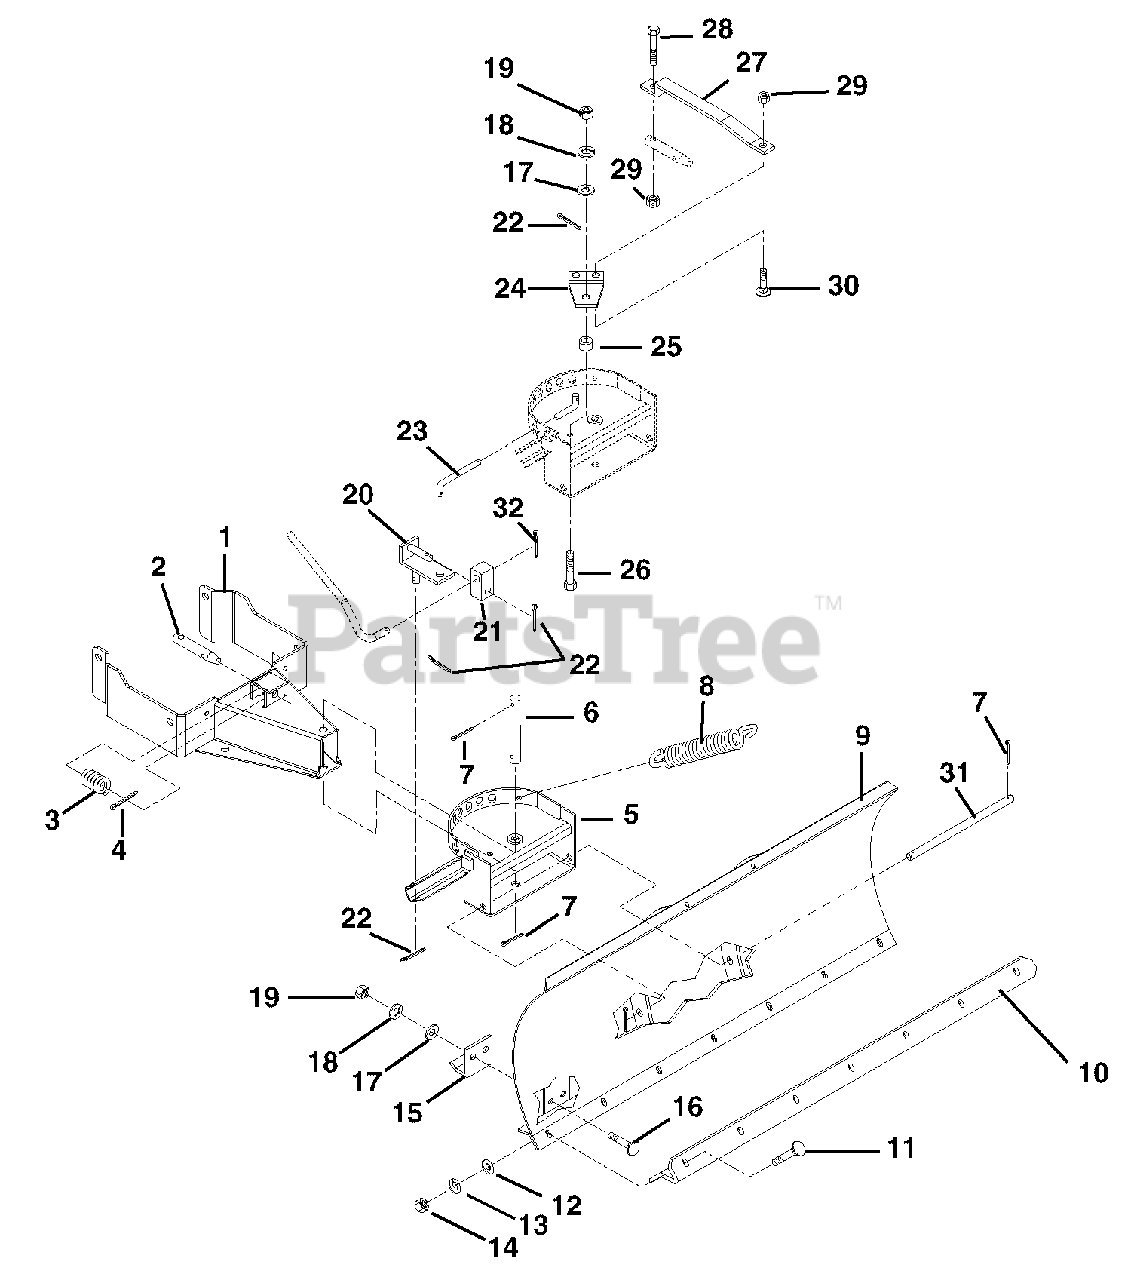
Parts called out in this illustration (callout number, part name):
1	Frame-Push
2	Latch Pin
3	Spring-Compression .080 x .85 x 1.44
4	Pin-Cotter .12 x 1.00
7	Pin-Cotter .12 x 1.00
8	Spring- Tension .187 x .50 x 9.94
10	Wear Plate
11	Bolt-Round Head Square Neck .31-18 x 1.00
12	Washer-Flat-Steel .38 x .845 .083
13	Washer-Lock .31 x .078 Regulator
14	Nut-Hex .38-16 Grade 2
15	Skid Shoe
16	Bolt-Round Head Square Neck .38-16 x 1.0
17	Washer-Flat Steel .438 x 1.0 x .083
18	Washer-Lock .375 x .094
19	Nut-Hex .375-16 Grade 2
21	Universal Block Joint
22	Pin-Cotter .12 x .75
24	Pivot Plate
25	Spacer .406 x .749 x .162
26	Bolt-Hex. .38-16 x 1.00 Grade 5
28	Bolt-Hex .31-18 x 1.25 Grade 5
29	Nut-Locking Center .31-18
30	Bolt-Round Head Square Short Neck .31-18 x .75 Grade 5
32	Pin-Hair Internal .08 x .18 x 1.18
